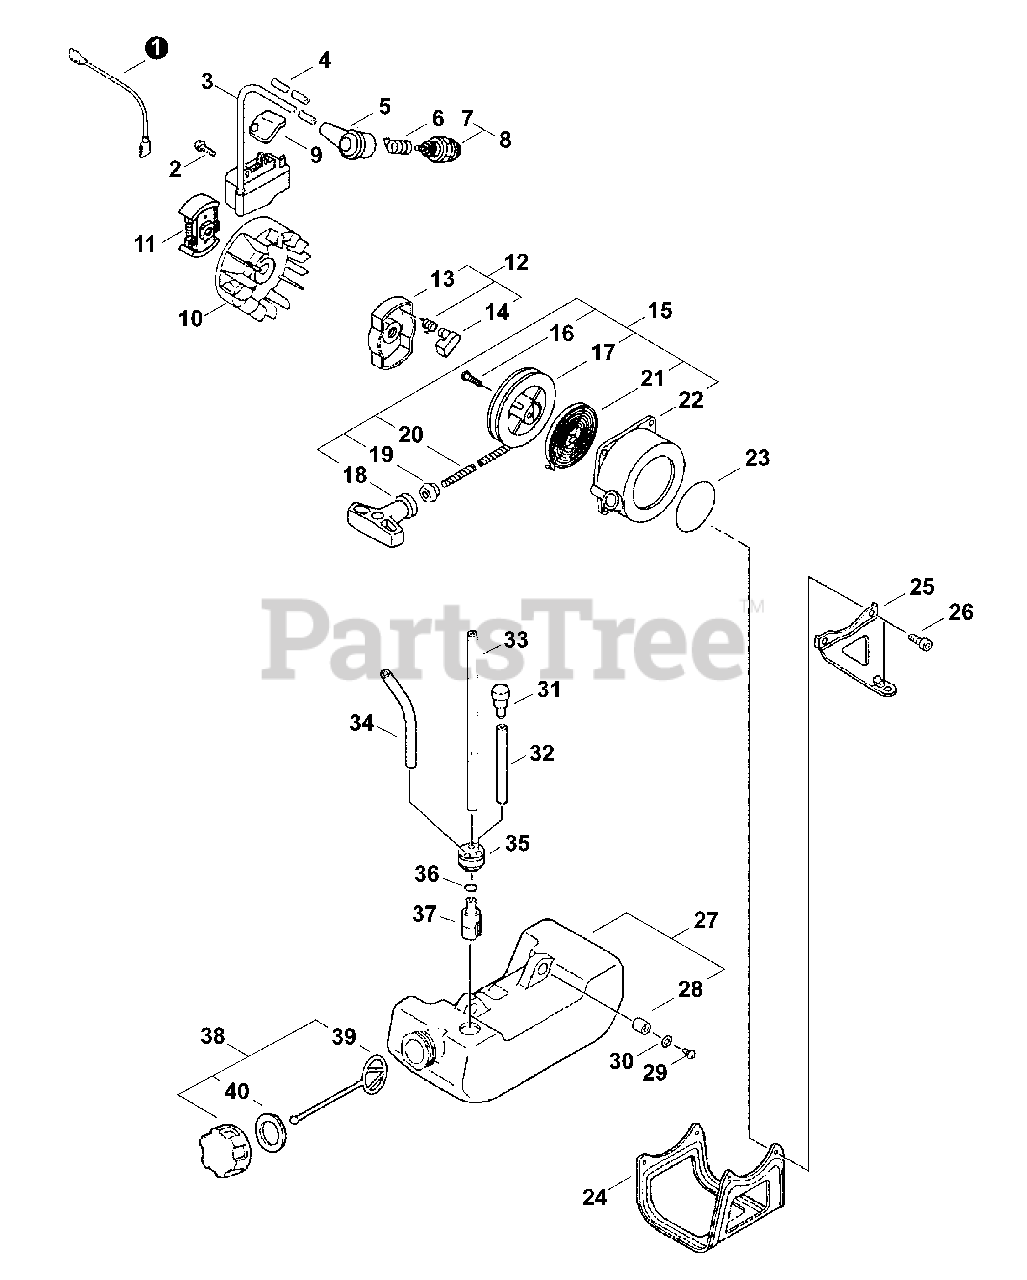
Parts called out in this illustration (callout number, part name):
1	LEAD - GROUND
2	BOLT 4×20
3	COIL, IGNITION
4	TUBE, INSULATOR
5	CAP, SPARK PLUG
6	TERMINAL, SPARK PLUG
7	SPARK PLUG - BPM8Y
8	SPARK PLUG - BPMR8Y
10	FLYWHEEL
11	CLUTCH ASSY
12	PAWL ASSY, STARTER
13	SPRING, RETURN
14	PAWL, STARTER - BLACK
15	STARTER ASSY, RECOIL
16	SCREW
17	REEL, ROPE
18	GRIP, STARTER
19	GUIDE, ROPE
20	ROPE, STARTER 3×1000
21	SPRING, RECOIL
22	CASE, RECOIL STARTER
23	LABEL - ECHO
24	GUARD, FUEL TANK
25	SUPPORT, HANDLE
26	BOLT 4×16
27	TANK, FUEL
28	SPACER 6.2×7.8×6
29	SCREW 5×16
30	WASHER 5.5×12×0.8
31	VENT ASSY
32	PIPE, VENT
33	PIPE, FUEL
34	PIPE, FUEL 3×6×80 CLEAR
35	GROMMET, FUEL Ø5
36	CLIP 6 MM
37	FILTER, FUEL
38	CAP ASSY, FUEL
39	CONNECTOR, CAP
40	GASKET, FUEL CAP
